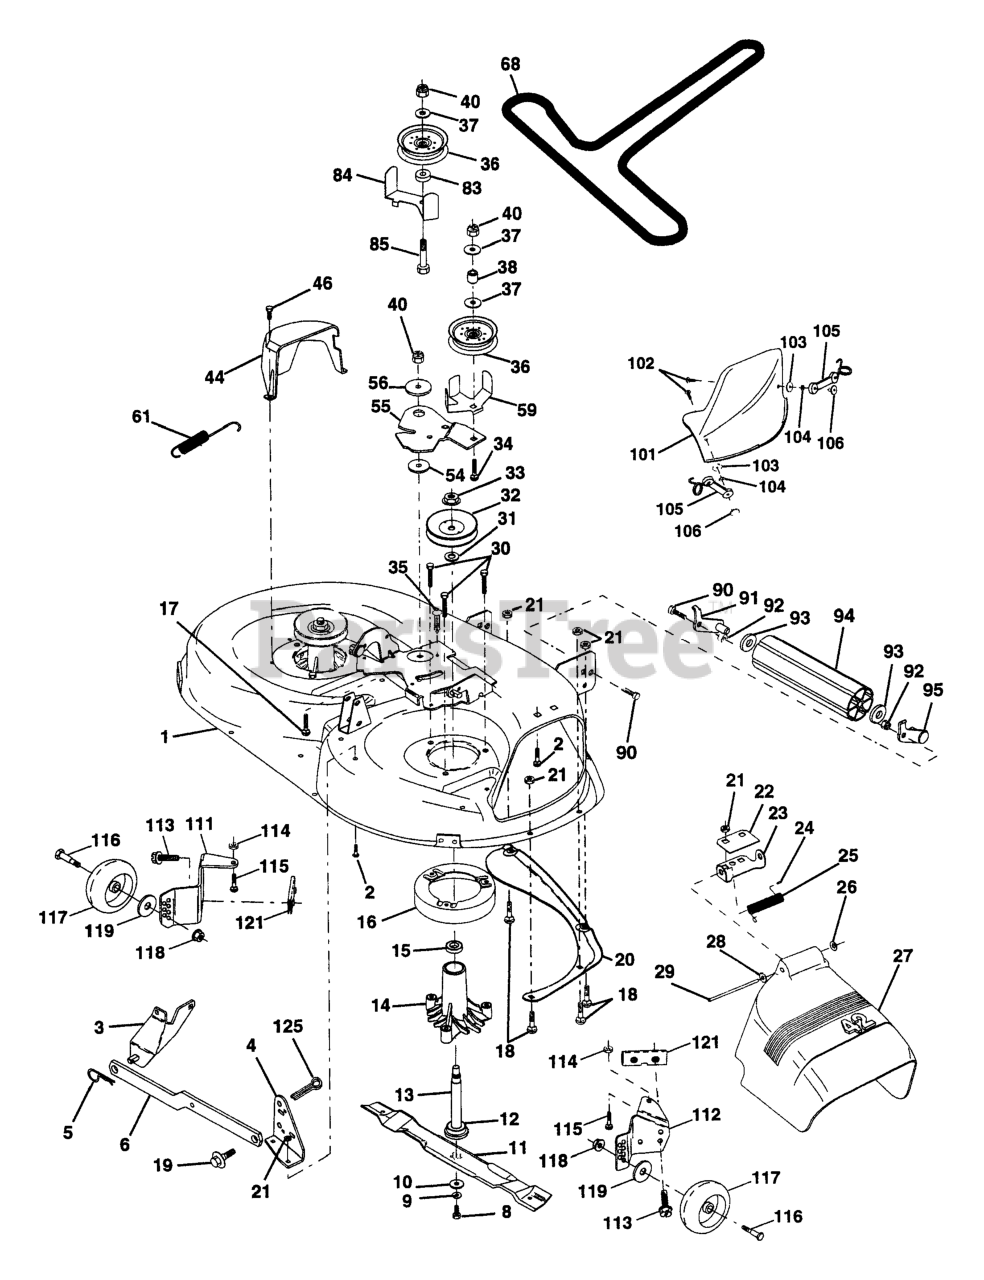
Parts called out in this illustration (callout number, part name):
1	DECK 42"
2	RP BOLT 5/16-18 X3/4 ZN/YEL GR
3	BRKT ASM SWAY BAR
4	BRKT DECK SW BAR
5	RETAINER-SPRNG RB
6	REAR SUSP ARM
8	BLADE BOLT
9	LOCKWASHER
10	WASHER.BLADE
11	BLADE.42".MULCH
12	BEARING.BALL.#6204.(MANDREL)
13	SHAFT ASM VENT
14	HOUSING.MANDREL.VENTED (MACHD)
16	STRIPPER
17	BOLT CARRIAGE
18	BOLT
19	BOLT SHD 5/16-18
20	BAFFLE
21	LOCKNUT
22	STIFFENER BRACKET
23	DEFLECTOR BRACKET
24	CAP-SLEEVE LT
25	SPRING TORSION
26	NUT PUSH M
27	SHIELD.DEFLECTOR.MOWER.42".BLK
28	Washer 11/32 X 5/8 X 16 Ga
29	ROD.HINGE
30	SCREW
31	WASHER
32	PULLEY/MANDREL
33	NUT
35	FASTENER.XMAS.TREE
36	FLAT IDLER PULLEY
37	WASHER
38	IDLER SPRING SPACER
44	GUARD MANDREL LH BLACK
46	SCREW.1/4-20X5/8
54	HARDENED WASHER
55	IDLER ARM
56	SPACER RETAINER
59	GUARD, BELT
61	SPRING EXTENSION
68	V-BELT TRIPATH
84	KEEPER BELT
85	BOLT
90	BOLT
91	BRACKET LH (A)
92	NUT
93	Washer 17/32 X 7/8 X 16 Ga
94	NOSE ROLLER
95	BRACKET RH (B)
101	COVER MULCH 42"
102	SCREW
104	LOCKWASHER #10
105	LATCH ASSEMBLY
106	WELDNUT
111	BRACKET
112	BRACKET
113	SCREW.THDROL.5/16-18X3/4.TTY
114	NUT
115	BOLT.CARR.5/16-18X1/2
116	BOLT, SHOULDER
117	WHEEL GAGE DONUT
118	LOCKNUT
119	WASHER.5/16.FLAT.STE.STD.
121	BRACKET.EXTRUDED.GAGE.WHEEL
125	Cotter Pin
